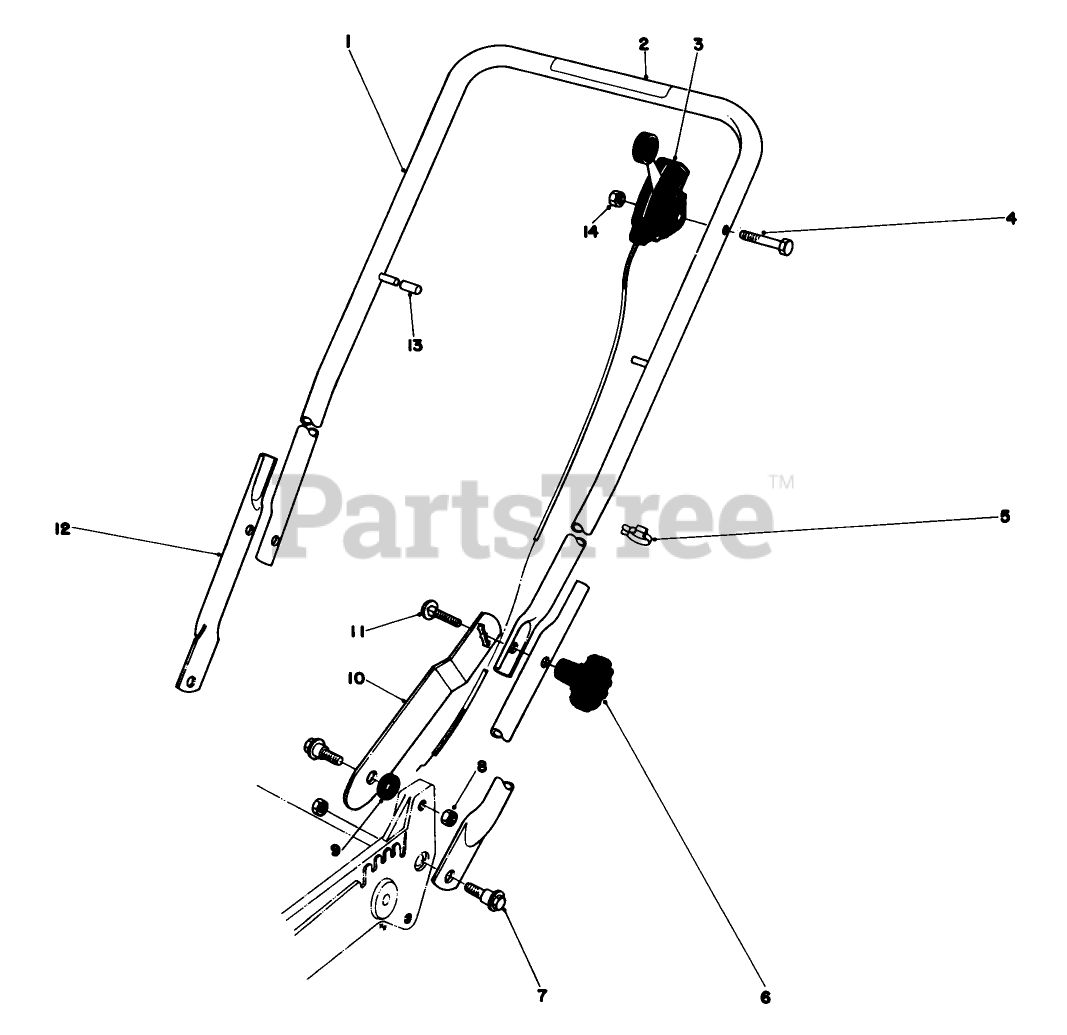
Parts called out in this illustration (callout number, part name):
4	SCREW-HH
5	BOWDEN CLIP
9	SPACER
11	BOLT-CAR
